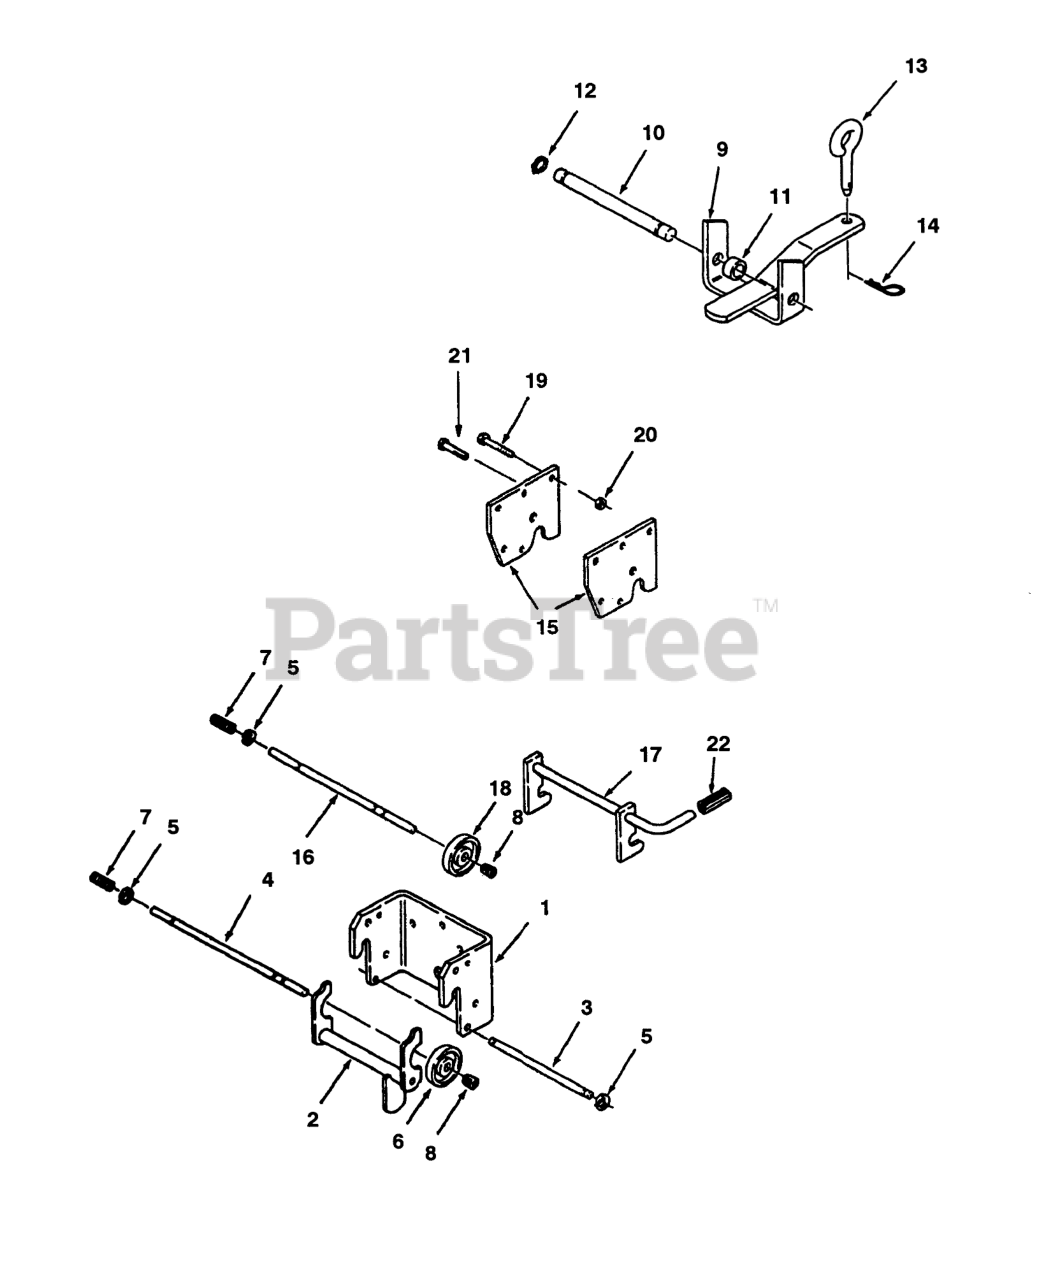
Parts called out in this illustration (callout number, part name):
1	Front Hitch
2	Assy-Latch
3	ROD-LATCH PIVOT
4	ROD-LOCK
5	RING-RETAINING
7	SPRING
8	CAP-ROD, PLUNGER
9	Hitch
10	PIN-STATIONARY HITCH
11	Spacer
12	E-RING
13	PIN-TOOL
14	Hairpin Cotter
15	Hitch Plate
16	ROD-MID HITCH
17	MID HITCH ASM
18	ROD-LOCK
19	SCREW-HH
20	NUT-LOCK, NI
21	SCREW-HH
22	GRIP
